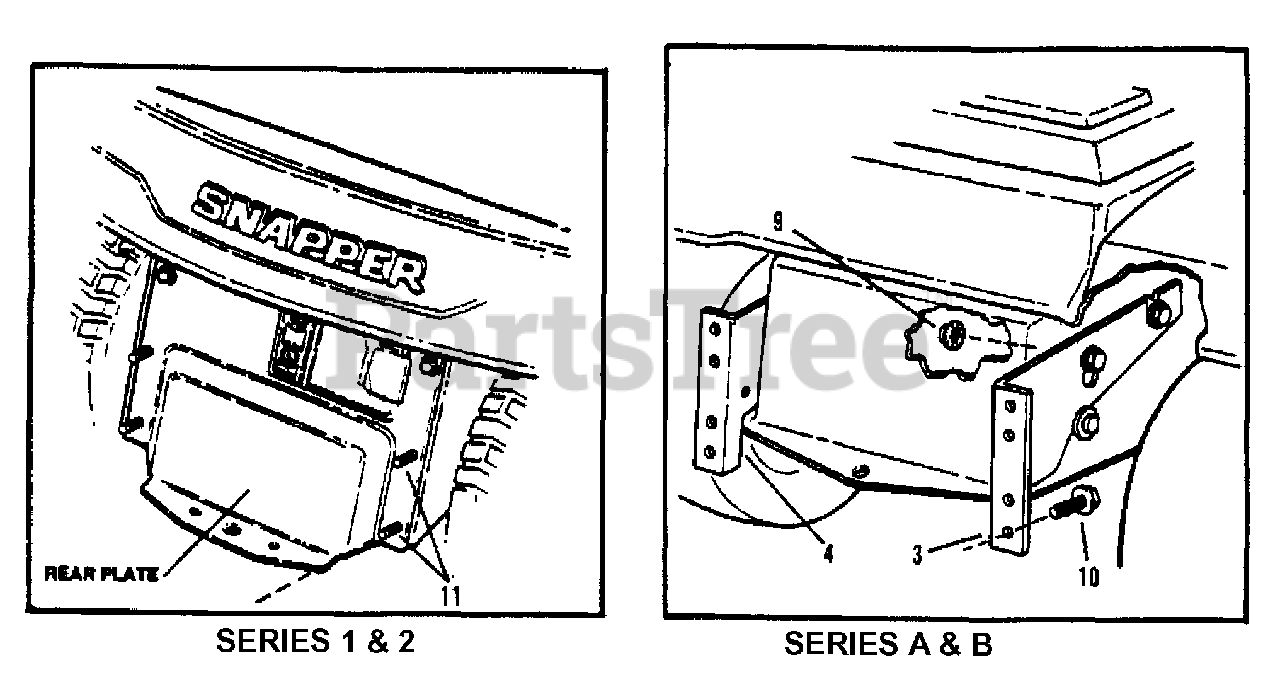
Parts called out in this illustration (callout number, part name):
3	SUPPORT, Stand-Up Tube (R.H.)
4	SUPPORT, Stand-Up Tube (L.H.)
9	NUT, 5/16-18 Hex Flange Lock, Grade 5
10	BOLT, 5/16-18 x 2", Hex Flange Lock, Grade 5
11	BOLT, 5/16-18 x 1", Hex Flange Lock, Grade 5
